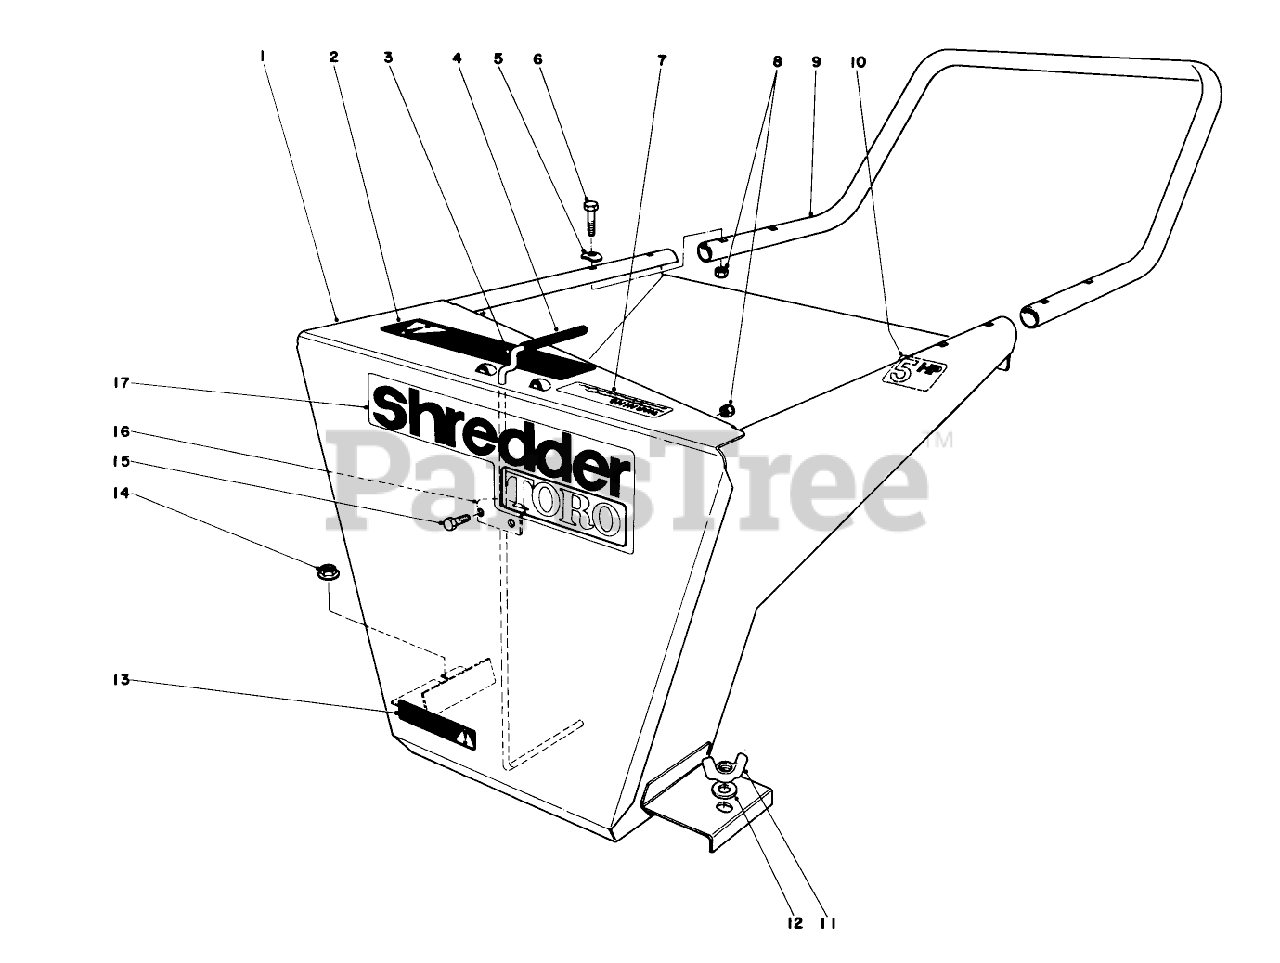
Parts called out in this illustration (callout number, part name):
1	Hopper
2	Caution Decal
3	Feeder Rod w/Grip
4	Handle Grip
5	Bent Washer
6	SCREW-HH
7	Warning Decal
8	NUT-LOCK, CONE
9	Handle
10	Decal
11	Wing Nut
12	WASHER-FLAT
13	Decal-warning
14	Flange Locknut
15	SCREW-HH
16	Feeder Rod Bracket
17	Logo Decal
